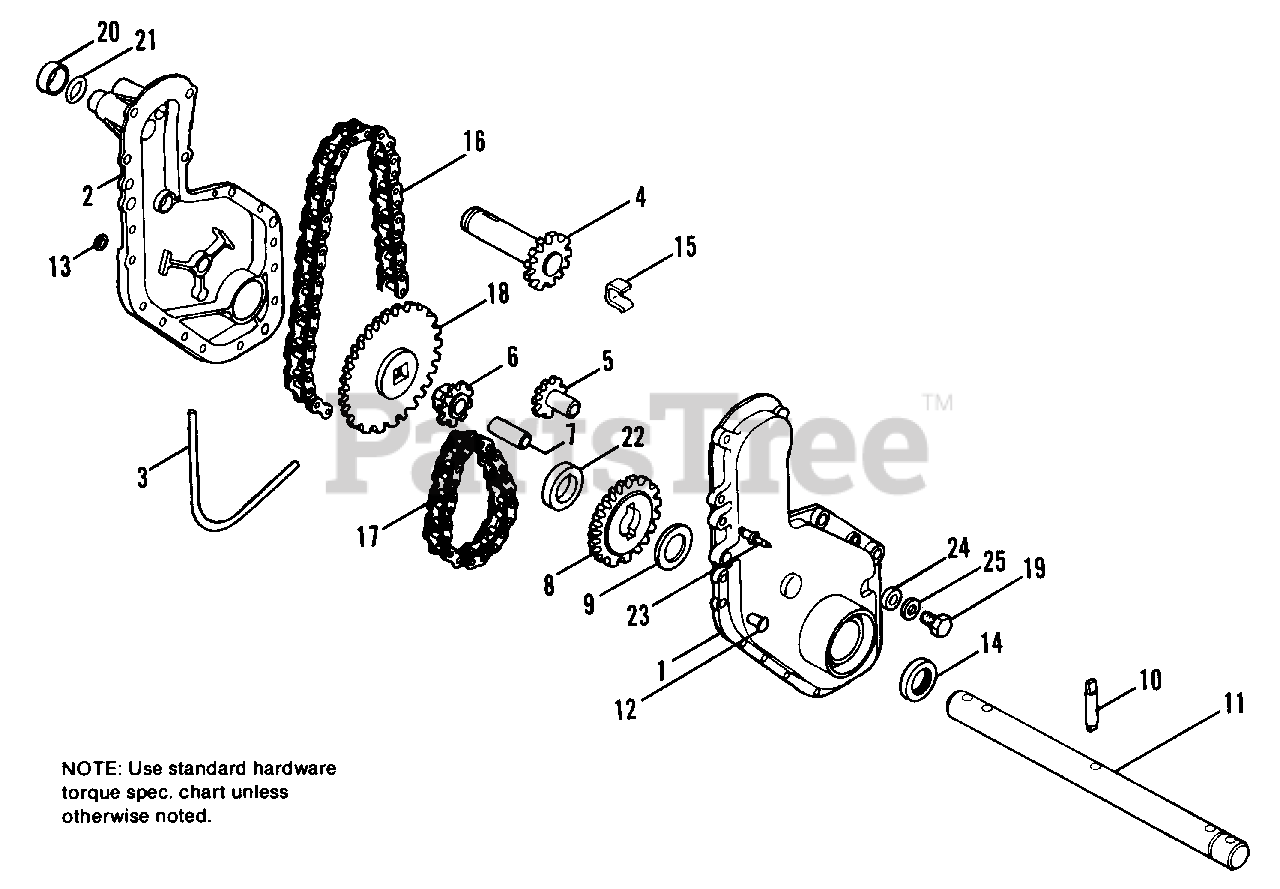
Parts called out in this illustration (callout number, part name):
1	CHAIN CASE-R.H.
2	CHAIN CASE-L.H. w/Bearing
4	INPUT SHAFT ASSEMBLY
5	IDLER SPROCKET-9 Tooth
6	SPROCKET-10 Tooth
7	SHAFT-Sprocket
8	SPROCKET-27 Tooth
9	THRUST WASHER
10	DRIVE PIN
16	#35 ROLLERLESS CHAIN
17	#35 ROLLER CHAIN
18	SPROCKET ASSEMBLY-42 Tooth
19	CAPSCREW, Hex Hd. 5/16-18 x 1/2 Plated
23	POP RIVET
24	NYLON WASHER
25	WASHER, Flat SAE 5/16 Plated
